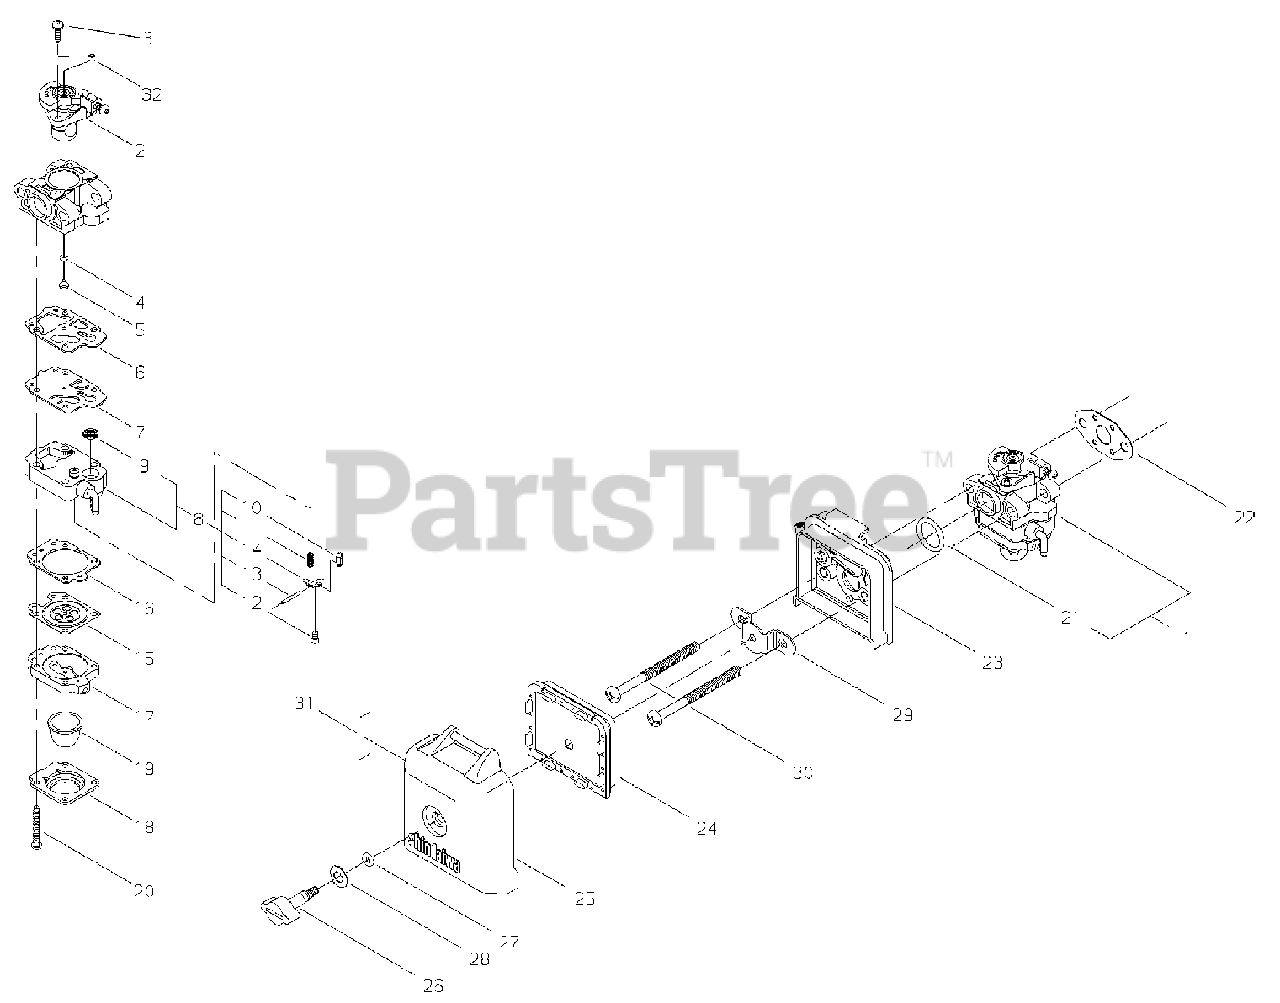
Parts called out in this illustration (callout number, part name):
2	VALVE, THROTTLE
3	SCREW
4	O-RING
5	JET, MAIN
6	GASKET, PUMP
7	DIAPHRAGM, PUMP
8	PUMP BODY ASSY
9	SCREEN, SPARK ARRESTOR
10	VALVE, INLET NEEDLE
11	SPRING, METERING LEVER
12	SCREW, METERING LEVER PIN
13	PIN, METERING LEVER
14	LEVER, METERING
15	DIAPHRAGM, METERING
16	GASKET, METERING
17	BASE, PURGE
18	COVER, PUMP
19	BULB, PURGE
20	SCREW, PUMP COVER
21	O-RING - 15
22	GASKET
23	CASE, AIR FILTER
24	FILTER, AIR - HEAVY DUTY
25	COVER, AIR FILTER
26	THUMBSCREW
27	O-RING
28	WASHER - CONICAL
29	PLATE, PREVENT
30	SCREW - 5X60
31	LABEL - CHOKE
32	PLAG
